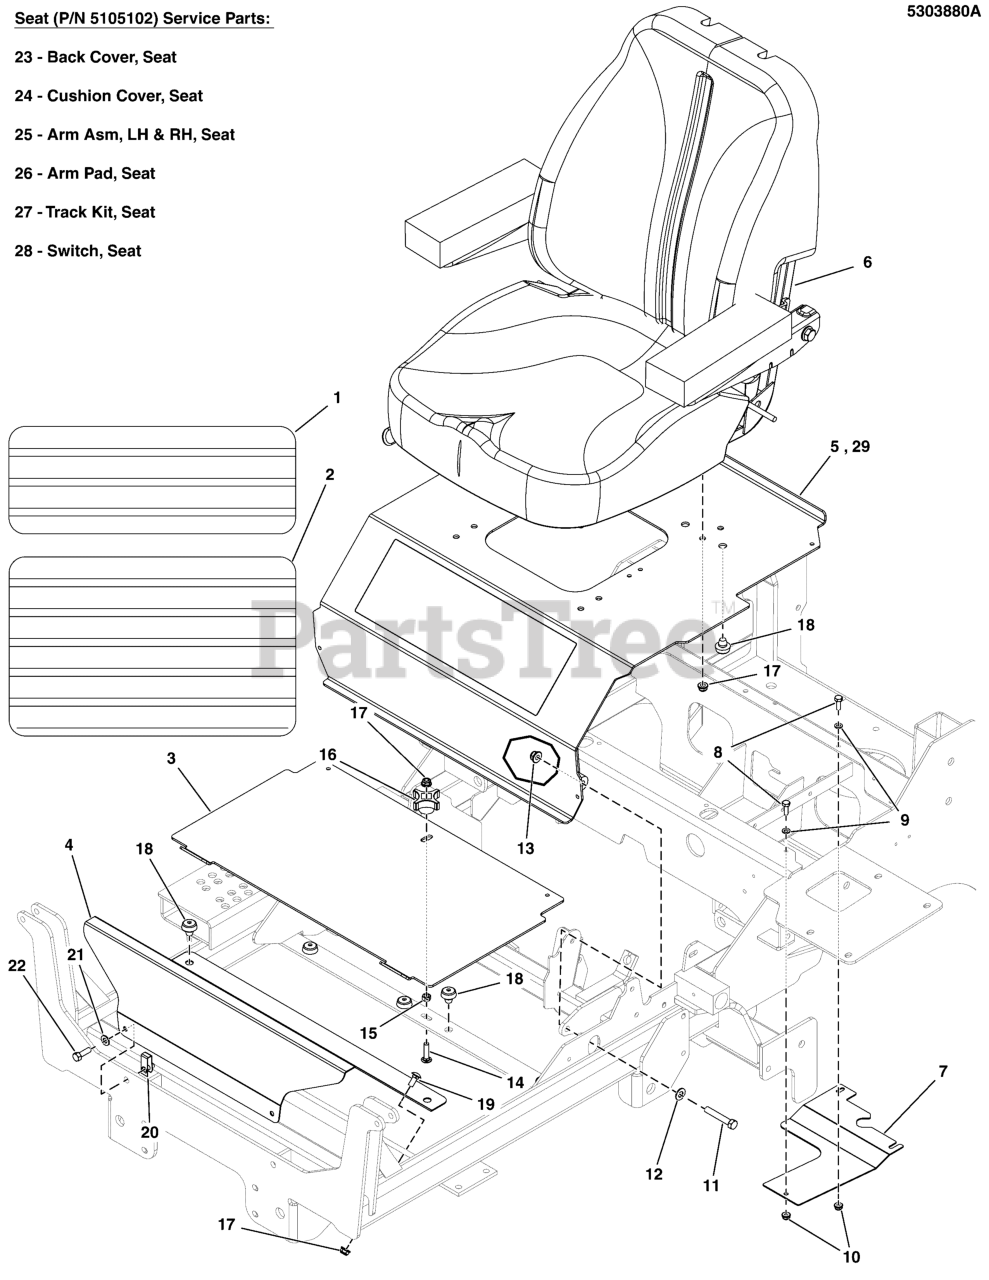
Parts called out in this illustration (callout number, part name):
1	SAFETY WALK, FLOOR REST, 16.00 X 6.00
2	SAFETY WALK, FLOOR PLATE, S50X, 10X17.13
3	PLATE, FLOOR, REMOVABLE, IS3100Z - RED
4	PLATE, FRONT FLOOR, IS3100Z - RED
5	ASSM, SEAT PLATE W/DECALS, IS3200Z-DOM (5412767B)
6	SEAT, HIGH BACK, SEAT'SINC, W/SWITCH
7	GUARD, DEBRIS, IS2100Z - BLK
8	BOLT, 1/4"-20 X 3/4" GD5 YZ
9	WASHER, 1/4 SAE
10	NUT, 1/4-20 HEX SERR. FLANGE
11	BOLT, 3/8-16 X 2-1/4" GD5 CZ
12	WASHER, 3/8 SAE
13	NUT, 3/8 - 16 HEX NYLOCK FLANGE
14	BOLT, 5/16-18 X 1-1/4, CARRIAGE, GD5, CZ
15	NUT, 5/16-1/8, HEX, CNTR LK, ZINC PHOS/OIL
16	KNOB-INT THR .312-18 4-ARM 2.12WD 1.06LG
17	NUT, 5/16-18 HEX NYLOCK FLANGE NUT
18	MNT, VBRTN, RBBR
19	BOLT, 5/16-18 X 3/4, CARRIAGE, GD5, CZ
20	BODY CLIP, 5/16-18 -1/4 MATERIAL
21	WASHER, 5/16" SAE
22	BOLT, 5/16-18 X 1" GRD5 YZ
23	BACK COVER
24	CUSHION COVER
25	SET OF ARMREST ASSEMBLY BLK/CHAR CAR FIB/HARBR GRY RED WELT
26	ARM PAD ASSEMBLY BLK/CHAR CAR FIB/HARBR GRY RED WELT
27	TRACK KIT
28	SWITCH, SEAT
29	ASSM, SEAT PLATE W/DECALS, IS3200Z-EXP (5412767B)
